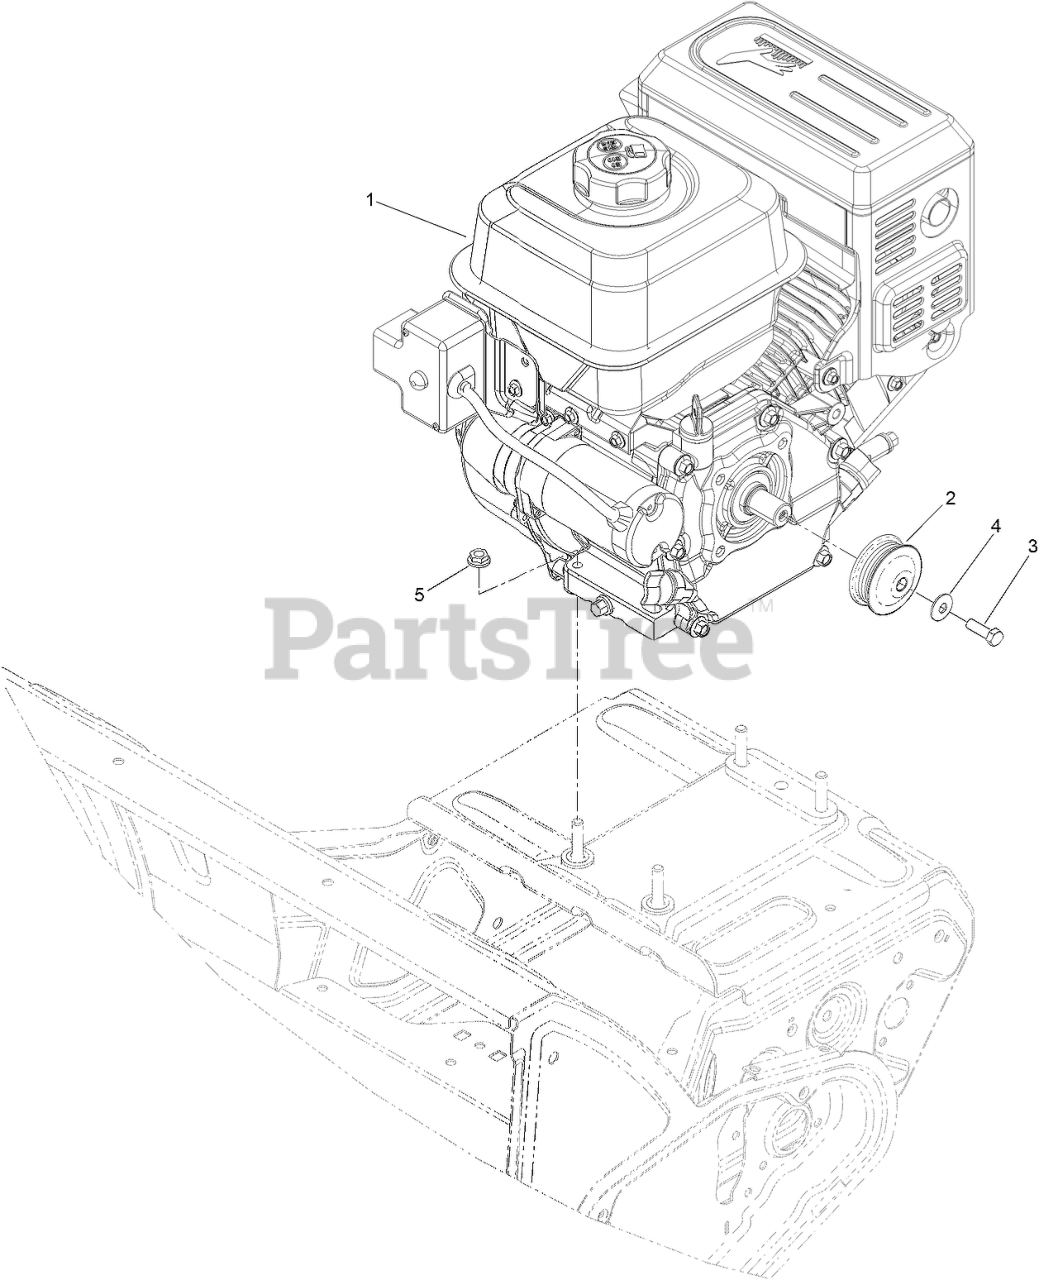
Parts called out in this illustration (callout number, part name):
1	ENGINE-G250FDS-2
2	PULLEY-ENGINE
3	SCREW-HH, PATCH
4	WASHER-BELLEVILLE
5	NUT-HF
